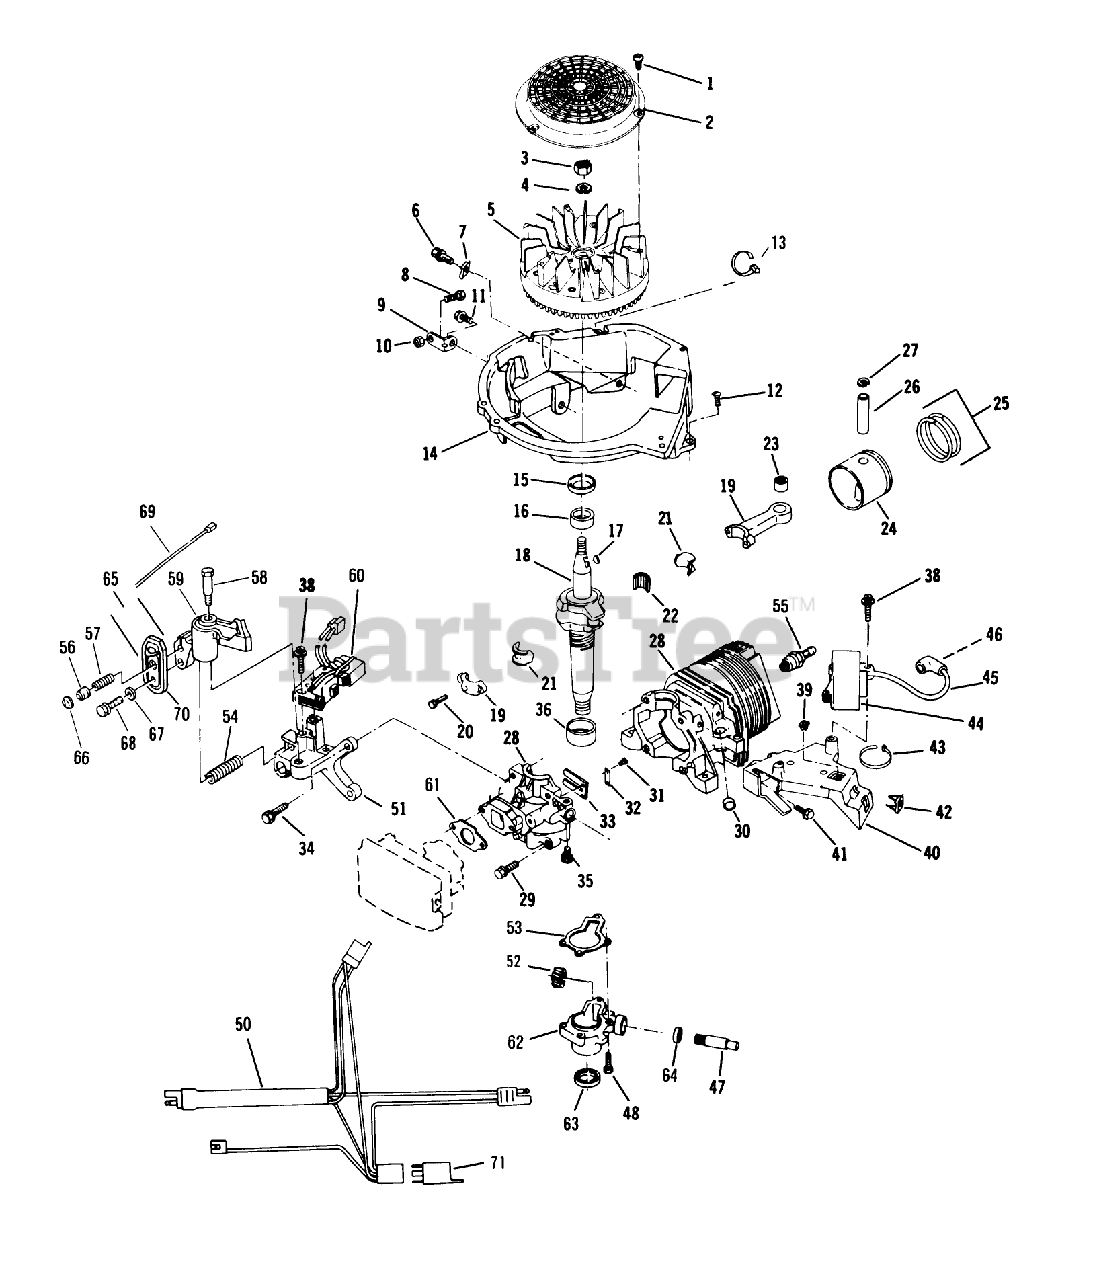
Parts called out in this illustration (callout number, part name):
1	SCREW F
2	SCREEN F'WHEEL S
3	NUT
5	FLYWHEEL ASSY F
6	SCREW-SEMS
8	BOLT F
10	NUT-LOCK F
12	SCREW F
14	BASE SHROUD F
15	SEAL-OIL
16	BEARING V
17	KEY
20	SCREW-HSH
21	LINER ASM
22	BEARING-NEEDLE
23	BEARING AY F
27	RING-RETAINING
29	SCREW S
30	PLUG-CORE VF
31	SCREW-HH
32	PLATE-BACKUP, REED
36	BEARING S
39	NUT-CLIP
40	C.D. BRKT F
42	NUT-CLIP
45	HT LEAD&COVER XEV
47	DR SHAFT,PTO S
51	BRACKET F
51	BRACKET-BRAKE F
53	GASKET S
54	SPRING-BRAKE
56	ACTUATOR-LEVER, BRAKE
57	SPRING
60	ALTERNATOR AY F
61	GASKET CARB S
63	SEAL-OIL
64	SEAL S
66	RETAINER S
67	WASHER
69	WIRE LEAD AY F
